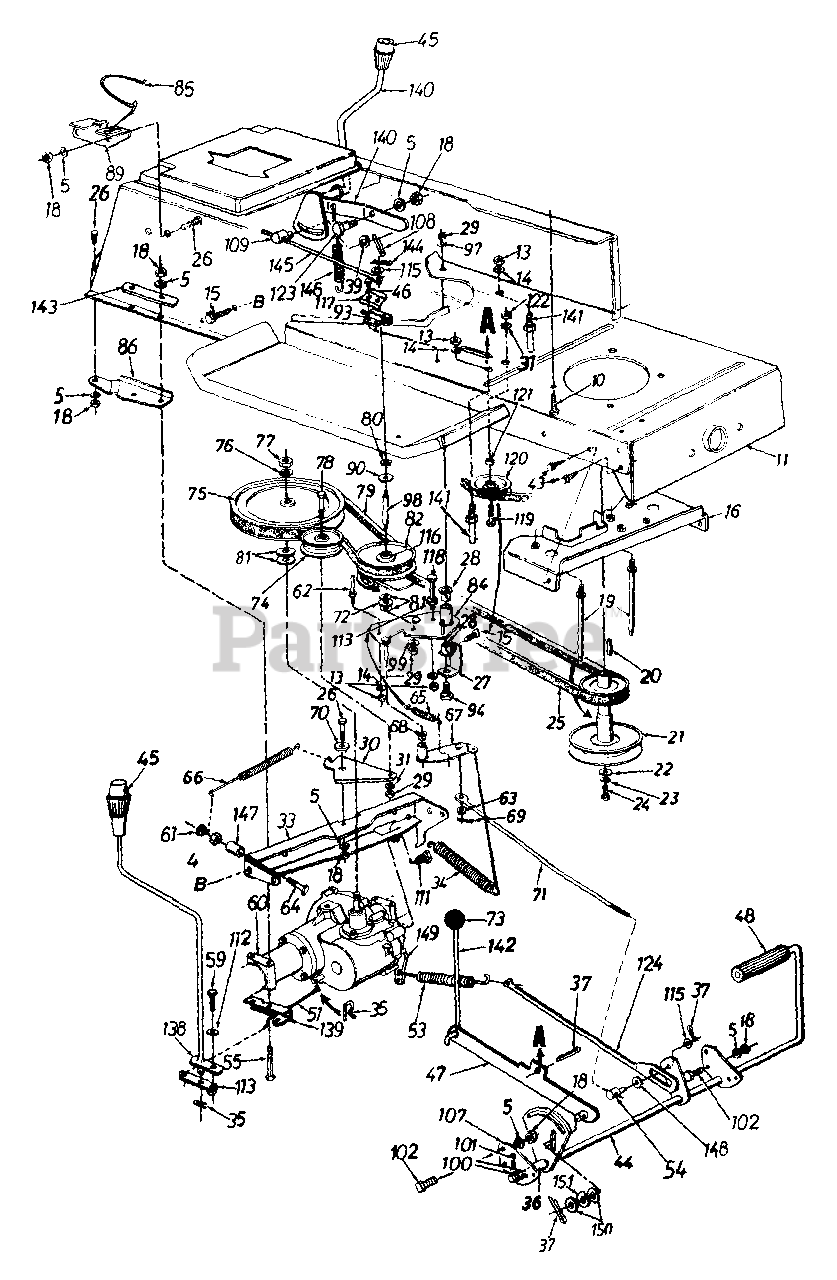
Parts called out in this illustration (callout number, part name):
4	Hex Nut 5/16-24 Thd.
5	L-Wash. 5/16" I.D.
10	Hex L-Wash. Tap Scr. 3/8-16 Thd.
14	L-Wash. 1/4" I.D.
15	Hex Wash. TT-Tap Scr. 5/16-18 x .62" Lg.
16	Belt Guard Brkt. Ass'y.
18	Hex Nut 5/16-18 Thd.
19	Belt Guard Stud
20	Sq. Key 1/4" x 1/4" x 2.00"
21	Engine Pulley
22	Fl-Wash. 7/16" I.D. x 1.25"
23	L-Wash. 7/16" I.D.
24	Hex Bolt 7/16-20 x 1.50" Lg.
25	Variable-Speed Belt
26	Hex Bolt 5/16-18 x .75" Lg.
27	Bearing Shaft Bracket Ass'y.
28	Flanged Nyliner Brg. .63" I.D. x .6" Lg.
29	Hex Nut 3/8-24 Thd.
30	Idler Bracket
31	L-Wash. 3/8" I.D.
33	Transaxle Support Brkt.
34	Ext. Spring .94" O.D. x 7.58"
35	Inter. Cotter Pin
36	Spacer .63" I.D.
37	Cotter Pin 1/8" Dia. x 1.0" Lg.
39	FL-Wash. .51" I.D. x .75"
43	Hex Wash. Hd. S-Tap Scr. 1/4-20 x .50" Lg.
44	Clutch/Brake Pedal Ass'y.
45	Shift Knob
46	Truss Mach. B-Tap Scr. #10 x .5" Lg.
47	Parking Brake Lockout Brkt. Ass'y.
48	Foot Pad
51	Shift Lever Rod
53	Ext. Spring 3.6"
54	Ferrule
55	Hex Bolt 5/16-18 x 3.25"
59	Hex Bolt 1/4-28 x .62" Lg.
60	Transaxle Complete
61	Hex L-Nut 1/4-20 Thd.
63	Fl-Wash. .34" I.D. x .68" O.D.
64	Hex Wash. TT-Tap Scr. 1/4-20 x 1.75"
65	Ext. Spring 2.59" Lg.
66	Ext. Spring .5" O.D. x 4.35"
68	Flanged Bearing
69	Cotter Pin 3/32" Dia.
70	Shoulder Spacer .27" Lg.
71	Speed Control Link
72	Truss Bearing .56 Dia. x 1.25"
73	Ball Knob
74	Fl-Idler Pulley 3.25" x .75"
75	"V"-Pulley
76	Bell-Wash. .567" I.D. x 1.125"
77	Hex Jam Nut 9/16-18 Thd.
78	Hex Bolt 3/8-24 x 1.75" Lg.
79	Variable Speed Belt
80	Snap Ring .56" Dia.
81	Fl-Wash. .56" I.D. x 1.0" O.D.
82	Variable Speed Pulley Ass'y. 5" O.D.
90	Teflon Washer .565" I.D.
93	Safety Switch (Clutch)
94	Shld. Bolt 3/8-24 x 3.12" Lg.
97	Bell-Wash. .38" I.D. x .88"
98	Shaft
99	Bell-Wash. .39" I.D. x 1.12"
100	Fl-Wash. .64" I.D. x .94"
101	Cotter Pin 1/8" Dia. x 1.25" Lg.
102	Hex Wash. Hd. Scr. 5/16-18 x .62" Lg.
109	Ferrule
111	Hex Wash. Tap Scr. 5/16 x 1.75" Lg.
112	Bell-Wash..265" I.D. x .75"
113	Shift Lever Link Ass'y.
115	Fl-Wash. .385" I.D. x.62"
116	Needle Brgs.
117	Switch Plate
118	Hex Bolt 1/4-20 x 3.5" Lg.
119	Hex Bolt 3/8-16 x 1.25" lg.
120	Fl-Idler w/Flanges 2.75" O.D.
121	Fl-Wash. .39" I.D. x 1.12" O.D.
122	Hex Nut 3/8-16 Thd.
123	Shld. Bolt .437" Dia. x .162"
124	Brake Rod Ass'y.
138	Shift Lever Ass'y.
139	Shift Lever Support Brkt.
140	Speed Selector Lever Ass'y.
141	Belt Guard Pin
142	Brake Lockout Rod
144	Cotter Pin 1/8" x 3/4" Lg.
145	Speed Selector Rod
146	Ext. Spring 3.97" Lg.
147	Spacer .326" I.D. x .47"
148	Fl-Wash. 5/8" I.D. x 1.25"
149	Actuating Arm
150	Fl-Wash. .385" I.D. x .87" O.D.
151	Wave Wash. .38" I.D. x .75"
